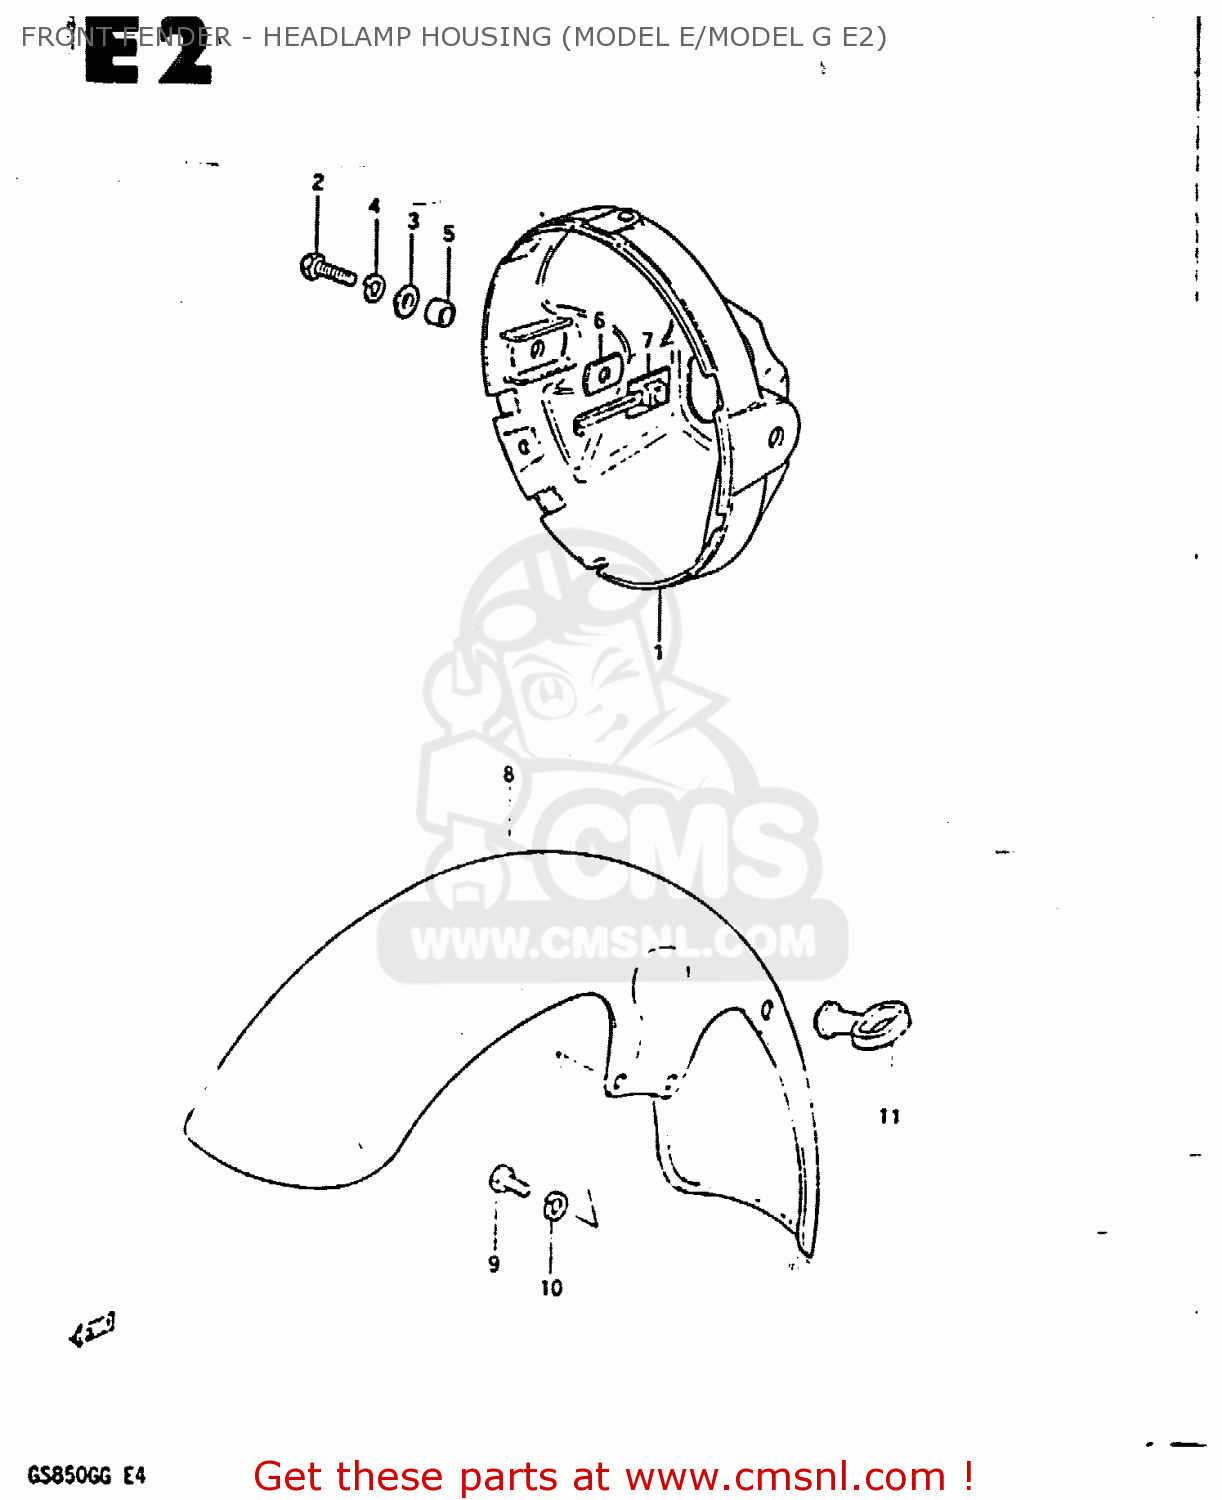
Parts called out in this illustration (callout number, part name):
1	HOUSING,HEADLAMP
2	BOLT
3	WASHER
4	LOCK WASHER
5	SPACER (8.8X12X7)
6	CUSHION
7	PLATE,HEADLAMP HOUSING
8	FENDER, FRONT (GOLD)
9	BOLT
10	LOCK WASHER
11	GUIDE,CABLE
